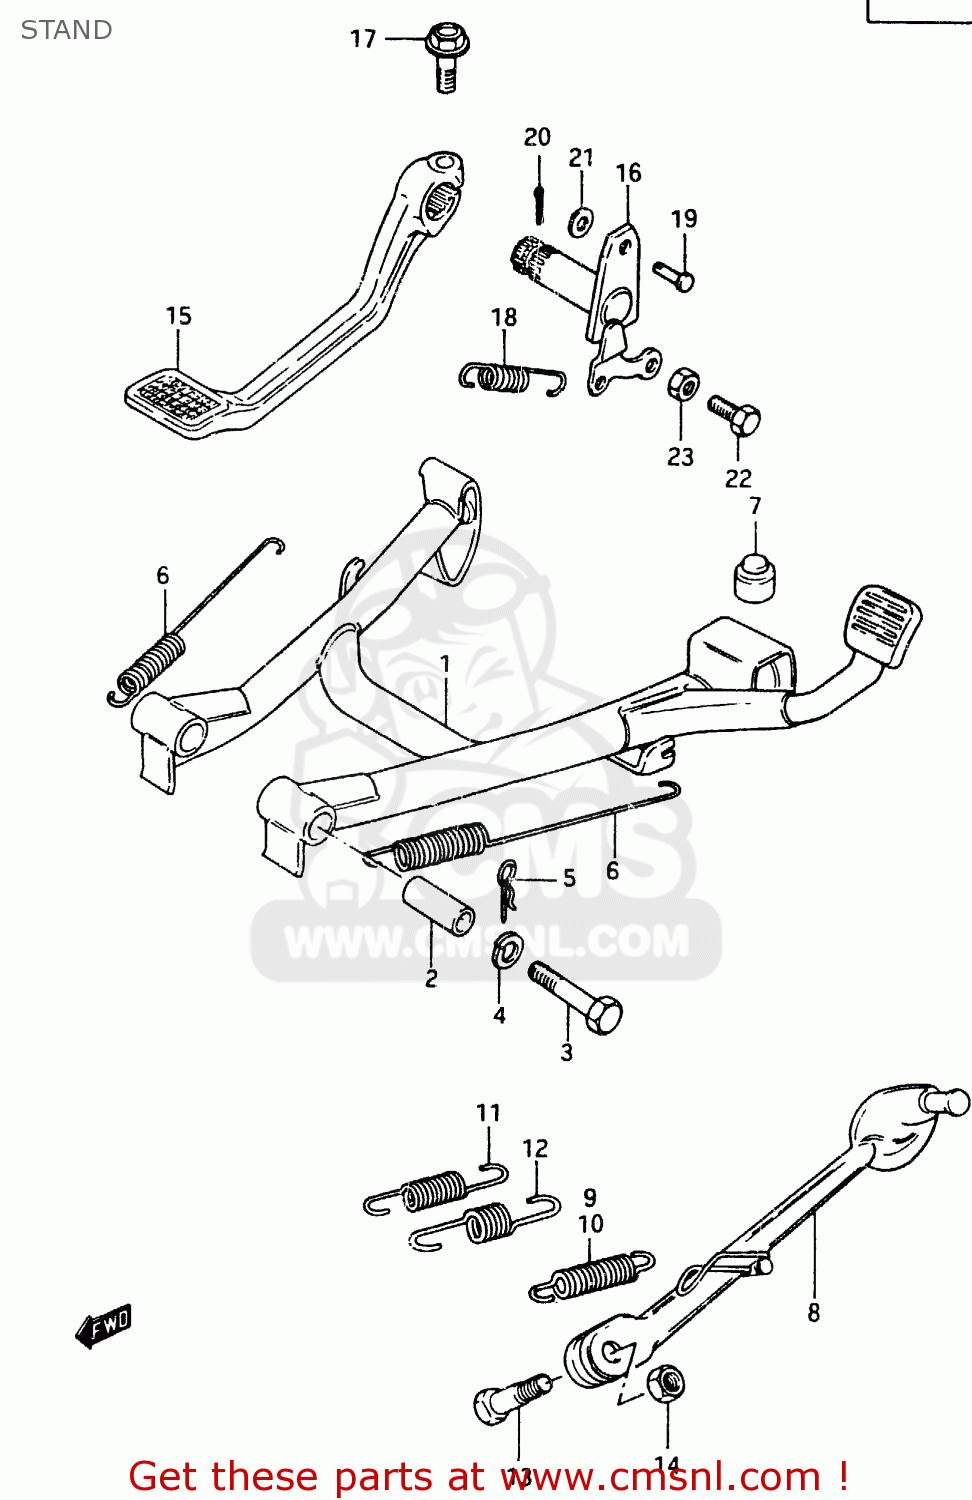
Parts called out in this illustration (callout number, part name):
1	STAND,CENTER
2	SPACER(10X16X38.8)
3	BOLT
4	WASHER,LOCK,10
5	CLIP
6	SPRING
7	CUSHION
8	STAND,SIDE
9	SPRING
10	SPRING
11	SPRING
12	SPRING
13	BOLT(10X32)
14	NUTM10X1.25X8
15	PEDAL,BRAKE
16	ARM,BRAKE PEDAL
17	BOLT
18	SPRING
19	PIN
20	PIN
21	WASHER
22	BOLT
23	NUT 6MM
